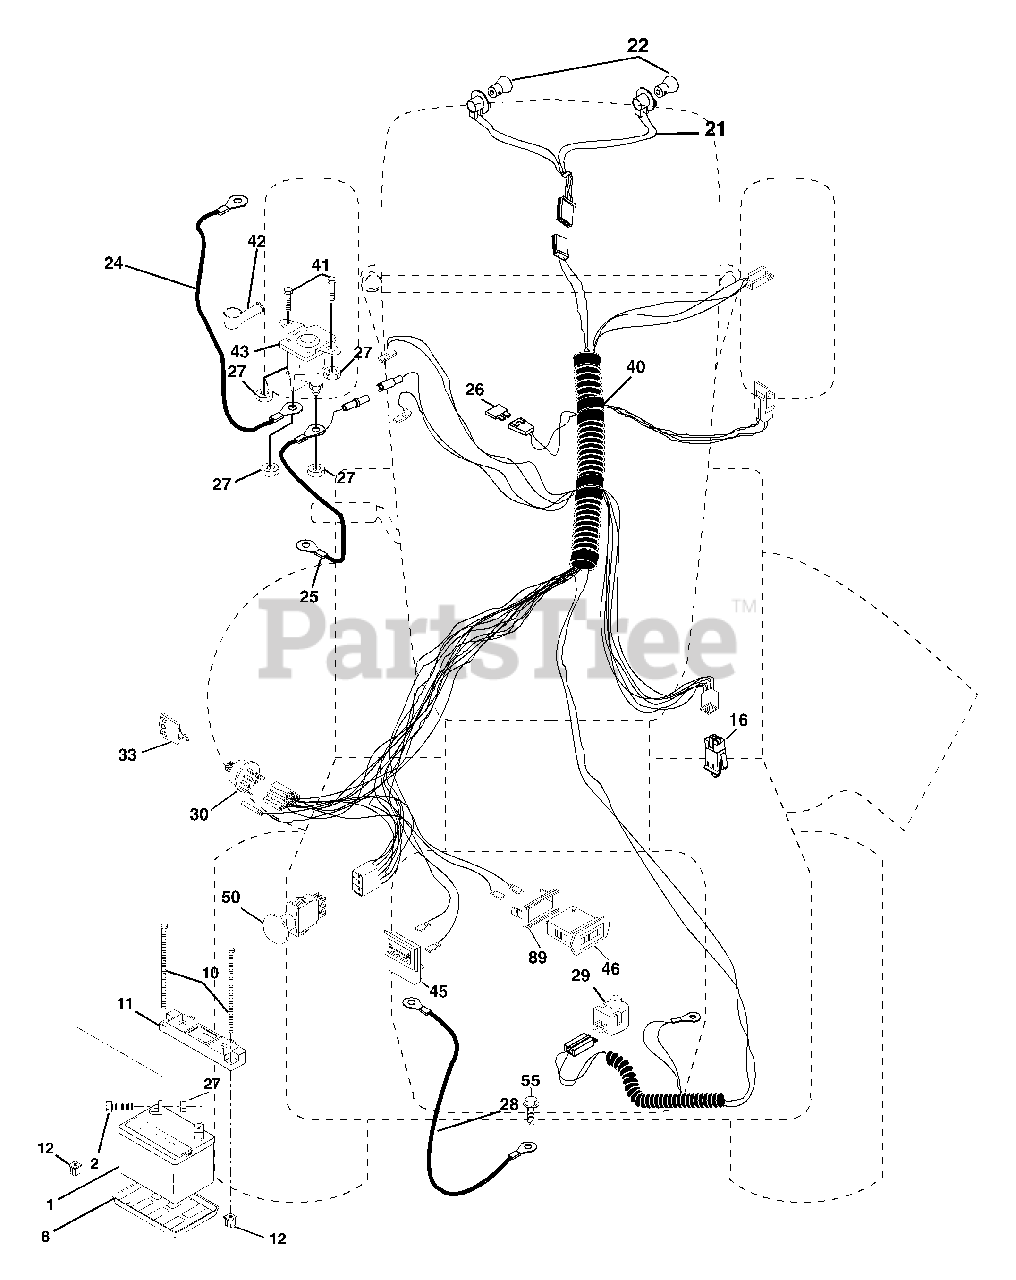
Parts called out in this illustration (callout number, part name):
1	Battery 12 Volt 35 AMP
2	Bolt Hex Hd 1/4-20 unc x 3/4
8	Tray Battery
10	Bolt Brt Frt 1/4-20 x 75 Ainc
11	Holddown Battery Front Mount
12	Nut Push Nylon 1/4" Battery Frt
16	Switch Interlock
21	Harness Asm Light W/4152j
22	Bulb Light #1156
24	Cable Battery 6 Ga. 11" red
25	Cable Battery 6 Ga. 22" red w/16 wire
27	Nut Keps Hex 1/4-20 unc
28	Cable Ground 6 Ga. 21" black
29	Switch Plunger Nc Gray
30	Switch Ign
33	Key Ign Molded Generic
40	Harness Ign.
41	Bolt Blk Fin Hex 1/4 - 20 x 1/2
42	Cover Terminal Red
43	Solenoid
45	Ammeter Rectangular 15 Amp
46	Meter Hour
50	Switch PTO
55	Screw Thdrol 5/16-18 x 1-1/2 Tyt
89	Bracket Snap-In Hourmeter
